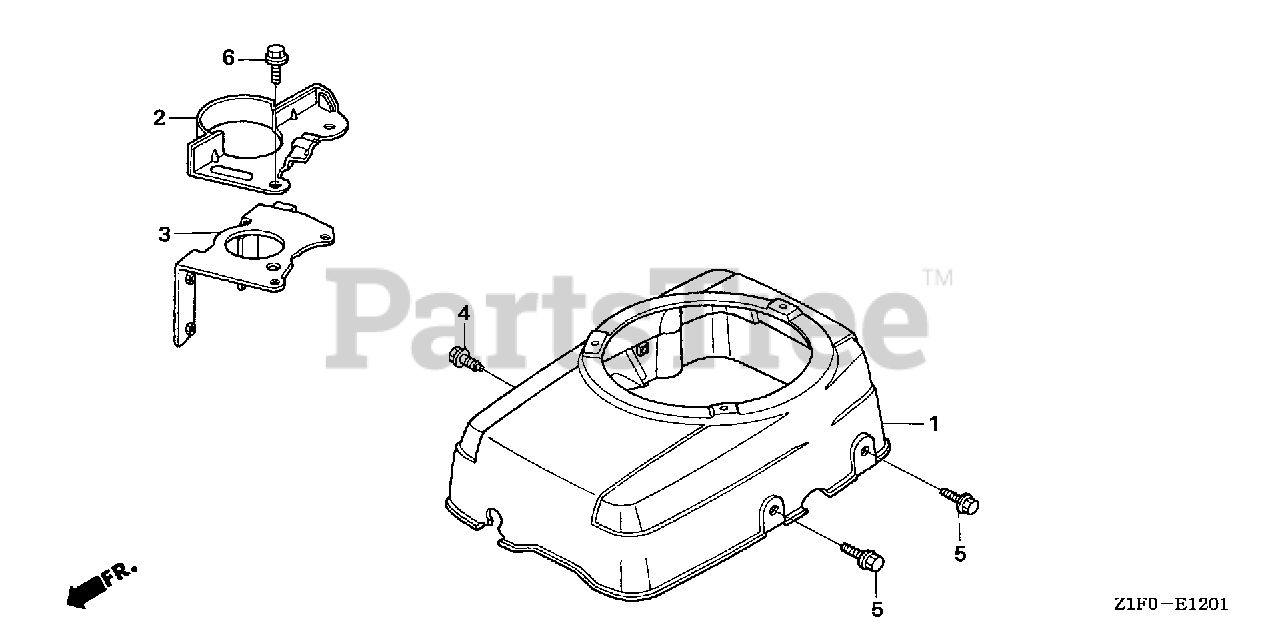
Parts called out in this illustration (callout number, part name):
1	COVER, FAN *R8* (Honda Code 7567951). (BRIGHT RED)
2	PLATE, SIDE
3	STAY, STARTER
4	BOLT, FLANGE (6X12) (CT200)
5	BOLT, FLANGE (8X16) Use from Engine SN 1000016.
6	BOLT, FLANGE (8X28)
